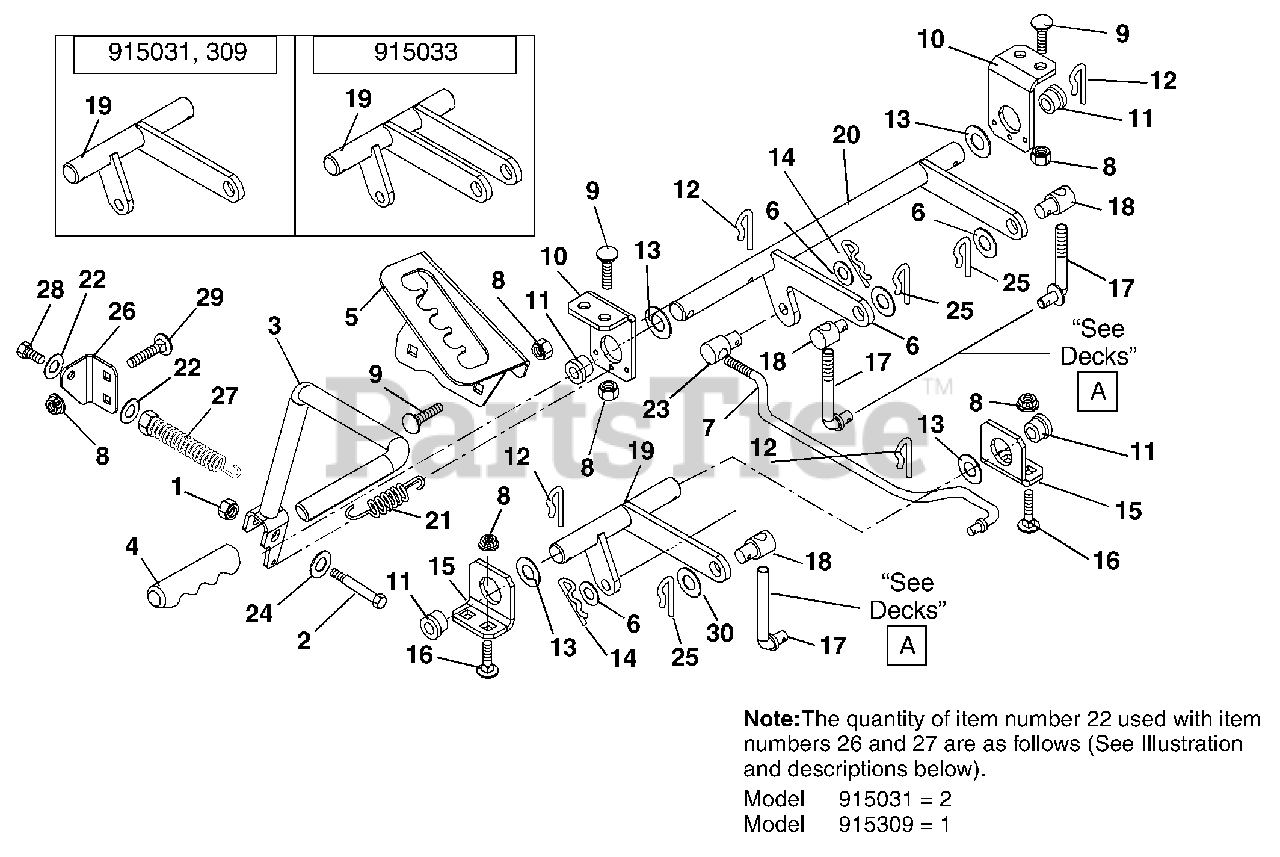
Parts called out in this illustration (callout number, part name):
1	NUT-LK-TOP-FLG .31-18 BLKZC
2	BOLT,SHLDR .38X1.25 .31-18 PLN
3	WLDM'T LIFT HANDLE
5	DETENT PLATE
6	WSHR-FL-STL.511X1.441X.125 YWZ
7	ROD, DECK LIFT
8	NUT-LK-TOP-FLG .38-16 BLKZC
9	BLT-RDHDSQNK .38-16X.75 G5BZ
10	BRACKET-HANGER
11	BSHG-FLG .750X1.000X.625X1.250
12	PIN, SPRING CLIP
13	@WSHR-FL-STL.812X1.50X.135YWZC
14	PIN, HAIR, EXT - #16 YWZC
15	BRACKET-PIVOT
16	BLT-RDHDSQNK .38-16X1.00 G5BZ
17	LINK, LIFT
18	TRUNNION-.50
19	WMT, FRONT LIFT
20	WMT, REAR LIFT
21	SPRING, EXTENSION
22	WSHR,FLT .438X1.00X.160 ZCC
23	PIVOT, ROD
24	WSHR,FLT .438X1.00X.160 ZCC
25	CLIP, SPRING
26	BKT, SPRING ANCHOR
27	SG-TENS .195X1.147X5.50
28	@BLT-HEX .38-16X1.50 GR5 YWZC
29	@BLT-RDHDSQNK .38-16X1.25 BKZC
30	@WSHR-FL-STL.563X1.38X.109YWZC
